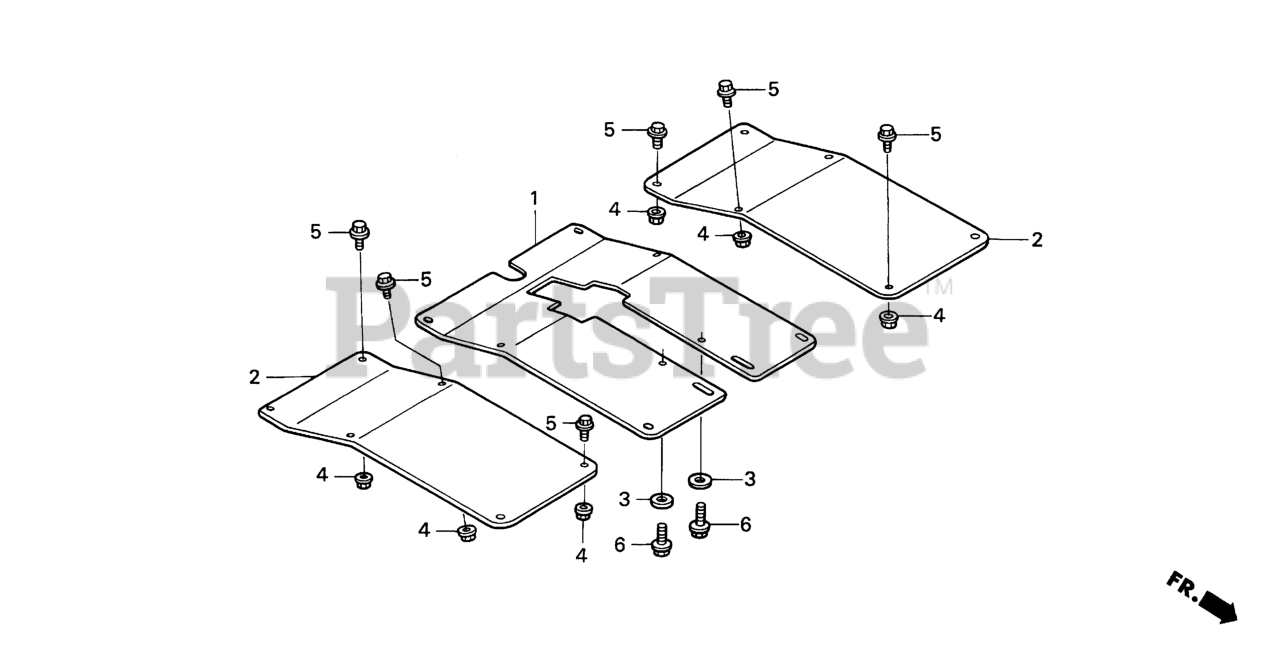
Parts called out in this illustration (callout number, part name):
1	FENDER, MAIN *R280* (POWER RED)
2	SUB-FENDER *R280* (POWER RED)
3	WASHER, LOCK (8MM)
4	NUT, FLANGE (6MM)
5	BOLT, FLANGE (6X10)
6	BOLT, FLANGE (8X18) Use from Frame SN 1256673.
